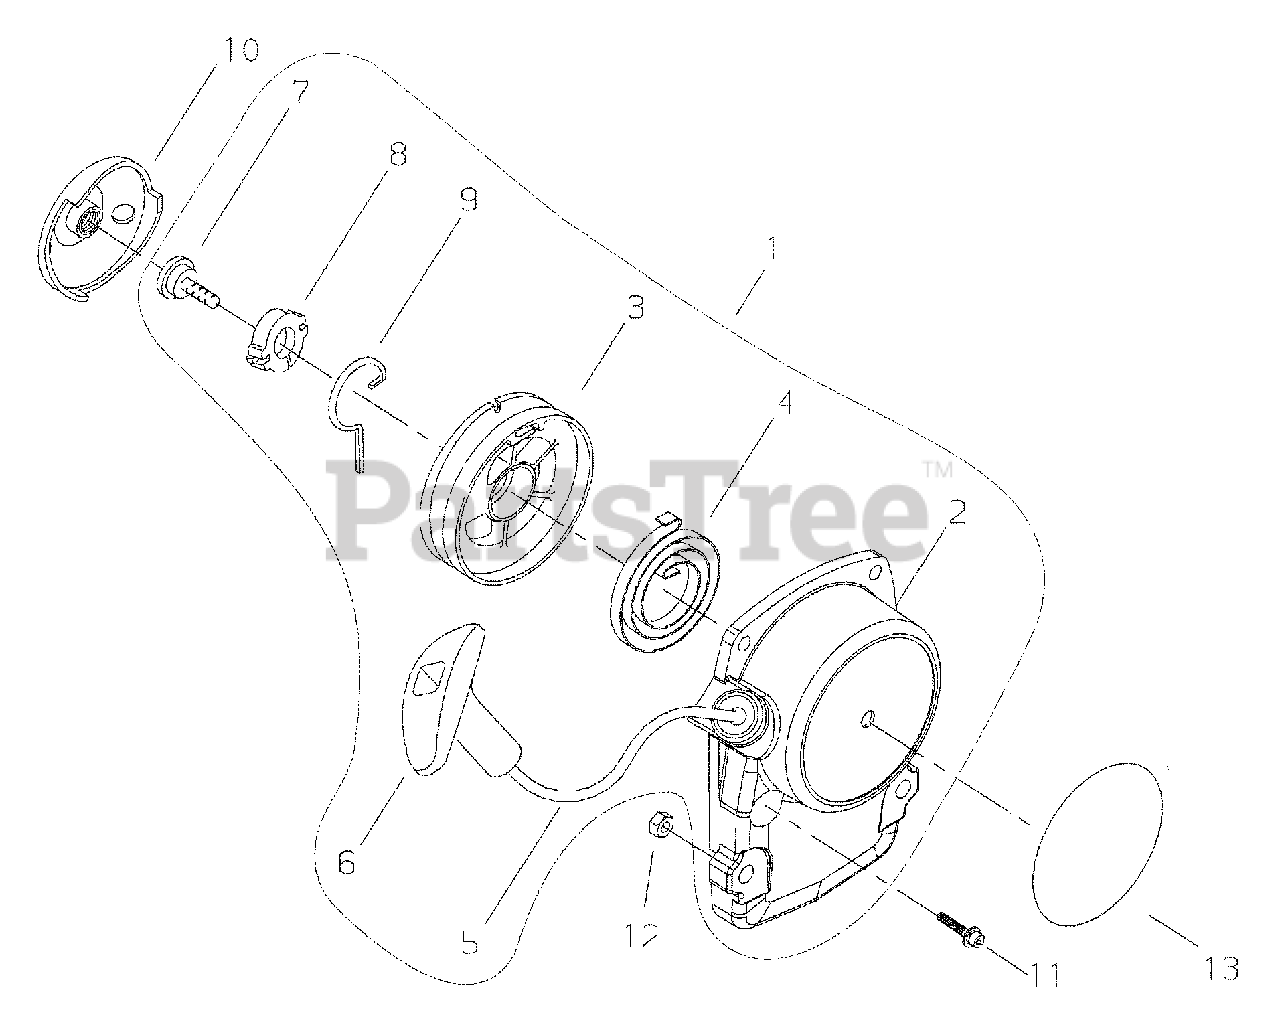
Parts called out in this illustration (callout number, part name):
1	STARTER ASSY
2	CASE, STARTER
3	REEL, ROPE
4	SPRING, REWIND
5	ROPE, STARTER
6	GRIP, STARTER
7	SCREW - 5
8	WASHER - 5
9	PAWL, STARTER
10	STARTER PAWL ASSY
11	SCREW - 4X16
13	LABEL - T242 PROFESSIONAL
